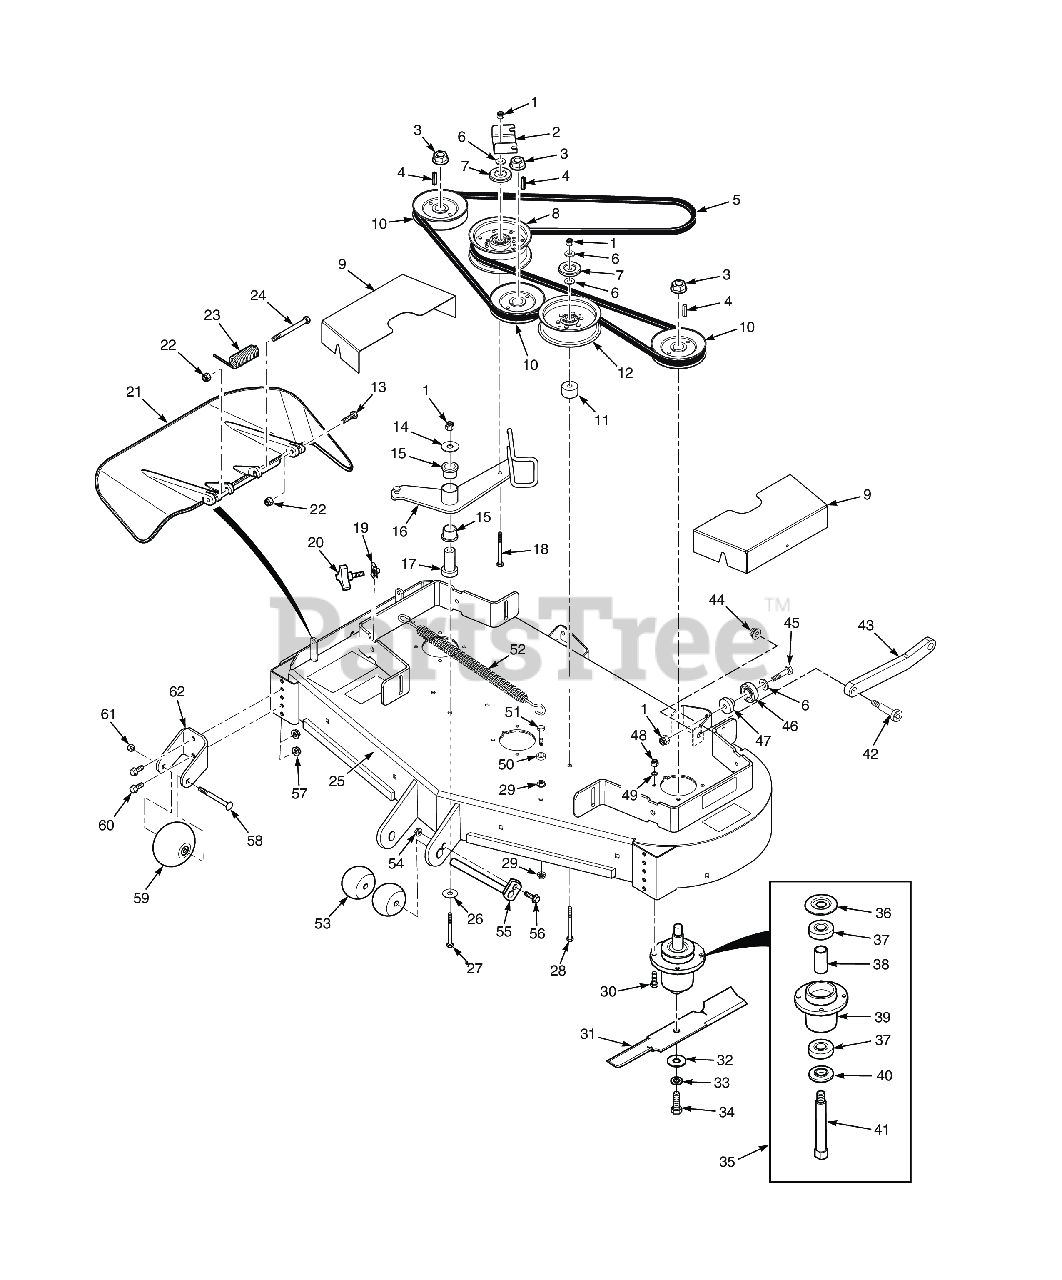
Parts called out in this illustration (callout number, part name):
1	HEX NUT, ELASTIC STOP LOCK, 3/8-16
2	Bracket, Belt Guide
3	Nut, 3/4-16 Spriral Lock
4	Key, 1/4 x 1/4 x 1.25" Pulley Mtg.
5	Belt, Cutter Deck
6	Flatwasher, 3/8 (.391 x .938 x .105 HD) Grade 8
7	Quick Pin, 5/16" Dia.
8	Pulley, Idler 5" Dia.
9	Belt Cover
10	Pulley, 5.73" OD - 25mm Bore
11	Spacer, Idler Pulley
12	Pulley, 5" Idler
13	Bolt, Hex Head 5/16-18 x 1-1/2" - Front
14	Flatwasher, 3/8-.406 x 1-1-1/2 x 7 Gauge
15	Bearing, Plastic
16	Idler Arm (incl. item #15)
17	Pivot, Idler
18	Capscrew, Hex Head 3/8-16 x 3.25"
19	U-Nut, 3/8-16
20	Knob, w/stud 3/8-16 x 1-1/4"
21	Discharge Chute Assy. SFZ52
22	HEX NUT, ELASTIC STOP LOCK, 5/16-18
23	Spring, Discharge Chute
24	Bolt, 5/16-18 x 4-3/4" Hex Head
25	Cutter Deck w/Decals, SMWZT-52
26	Flatwasher, 3/8-.406 x 2.25" x .1875
27	Capscrew, Hex Head 3/8-16 x 3-3/4"
28	Bolt, Hex Head, 3/8-16 x 3-1/2"
29	NUT, 3/8-16 SERRATED FLANGE HEX HEAD
30	Bolt, Hex Head 5/16-18 x 1-1/2" Grade 8
31	Cutter Blade, 18" (52V)
32	Flatwasher, 5/8-.688 x 1-3/4 x .134 HD
33	Lockwasher, 5/8" Spring
34	Bolt, Hex Head 5/8-11 x 1-1/2"
35	Spindle Assembly
36	Debris Shield
37	Bearing
38	Spacer, Bearing
39	Spindle Housing Assembly
40	Protector, Bearing
41	Shaft, Spindle
42	Bolt, Shoulder 1/2 x 3/8-16 x 2-3/4"
43	Pusharm
44	Nut, Flange Elastic Stop Nut, 3/8-16
45	Bolt, Hex Head 3/8-16 x 1-3/4" (Kohler EFI)
46	Bearing
47	Spacer, Bearing
48	Lock Nut, 5/16-18 Elastic Stop Grade 8
49	Lockwasher, 5/16 (.317 x .586 x .078) Helical Spring
50	SPACER, IDLER
51	Bolt, Hex Head 3/8-16 x 1-1/2" Grade 8 Black
52	Spring, L.H. Deck Drive
53	Wheel, Anti-Scalp
54	Nut, Serrated Flange 5/16-18 (Right Front Engine Mounting, Briggs and Kohler Only)
55	Shaft Weldment, Guide Roller
56	Bolt, Heax Head 5/16-18 x 1" (48V / 52V)
57	NUT, 3/8-16 SERRATED FLANGE HEX HEAD
58	Bolt, Hex Head 3/8-16 x 3-1/2"
59	Bolt, Carriage 3/8-16 x 4"
60	Capscrew, 3/8-16 x 1.0" Serrated Flange Hex Hd
61	Bolt, Hex Head 3/8-16 x 1" Ser. Flg.
62	Bracket, Anti-Scalp Wheel
